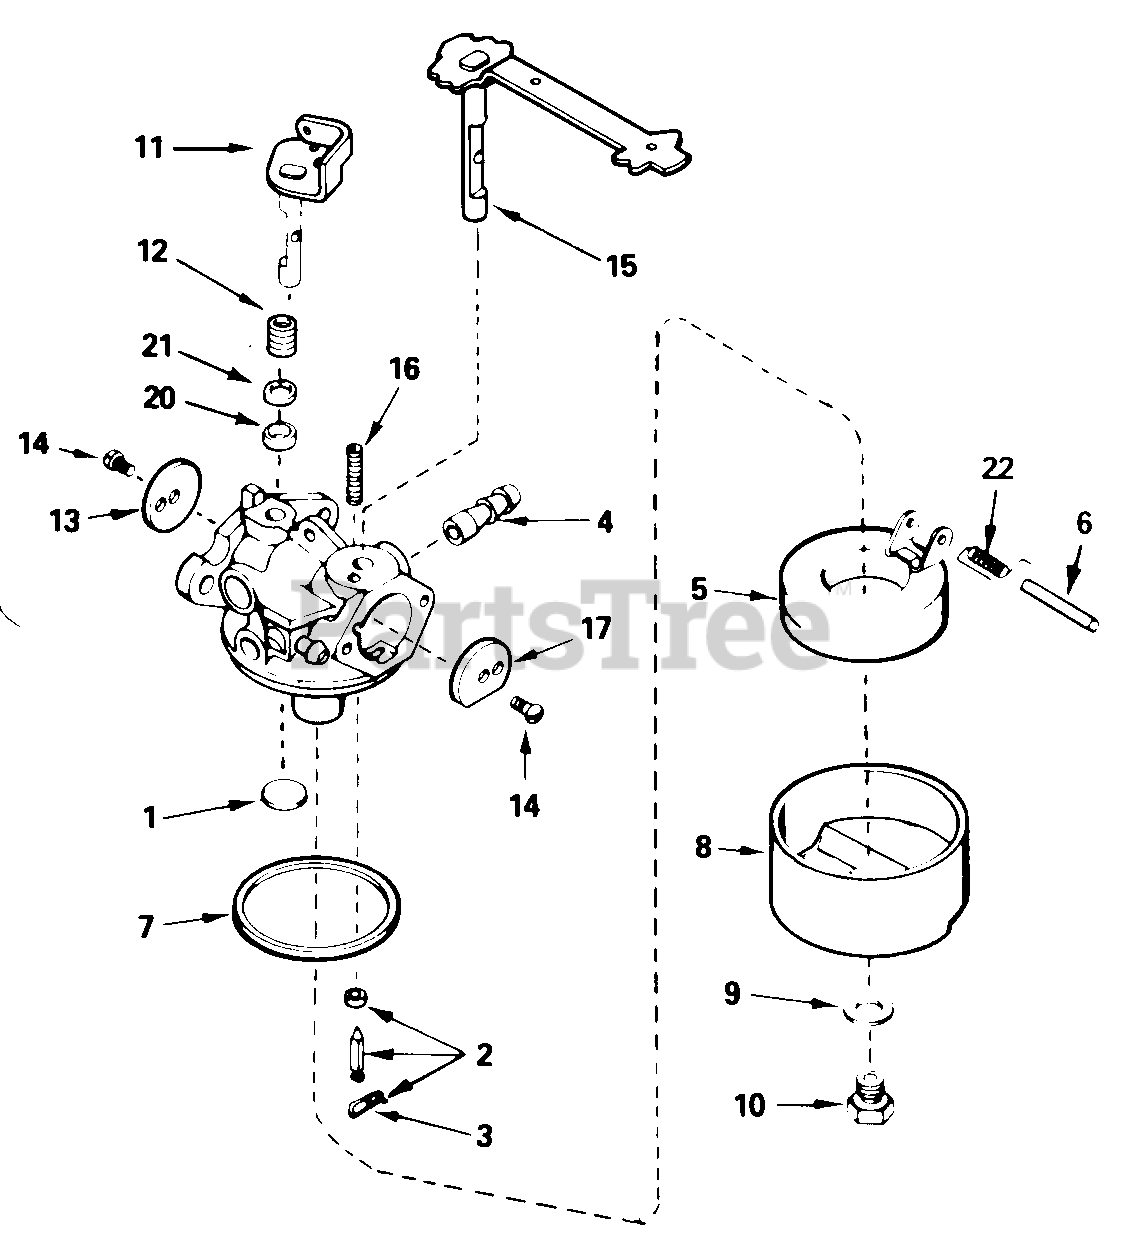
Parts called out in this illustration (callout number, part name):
1	Plug, Welch
2	Inlet Needle, Seat & Clip Ass'y.
3	Clip, Inlet Needle
4	Fitting, Fuel Inlet
5	Float, Carburetor
6	Shaft, Float
7	"O" Ring, Bowl-to-Body
8	Bowl, Float
9	Gasket, Bowl-to-Body
10	Nut, Float Bowl
11	Shaft & Lever Ass'y., Throttle
12	Spring, Throttle Return
13	Shutter, Throttle
14	Screw, Throttle & Choke Shutter
15	Shaft & Lever Ass'y., Choke
16	Spring, Choke Positioning
17	Shutter, Choke
20	Washer, Felt
21	Washer, Steel
22	Spring, Float Shaft
